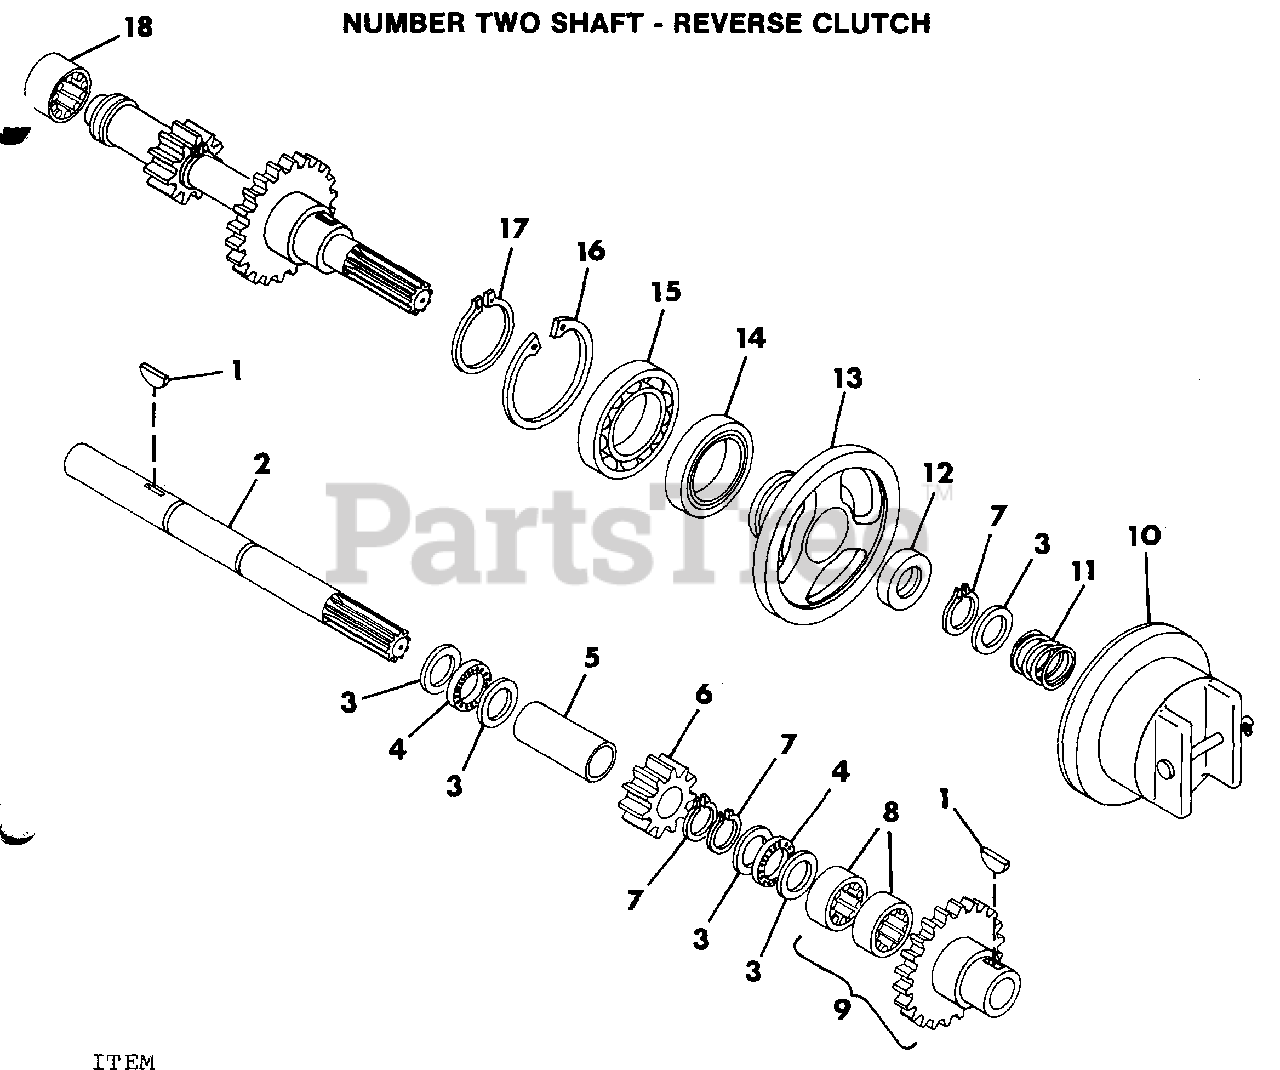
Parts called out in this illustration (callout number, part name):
1	KEY, WOODRUFF .187X.625 HARD #61
2	SHAFT, SPLINED REVERSE CLUTCH
3	RACE, BEARING THRUST
4	BEARING, NEEDLE THRUST
5	SPACER, #2 SHAFT
6	GEAR, 10 DP 16 TEETH X.750
7	RING, RETAINING .750 SHAFT
8	BEARING, NEEDLE .750X1.000X.500
9	ASM, REVERSE GEAR AND BEARING
10	NUMBER 11 - FWD-REV CLUTCH ASM.
11	SPRING, COMP. TYPE 1.0X.80X36 16/IN.
12	SEAL, OIL .750X1.625X.250
13	HUB, CLUTCH
14	SEAL, OIL 2.250X3.005X.375
15	BEARING, BALL 1.968X3.149X.629
16	RING, RETAINING 3.156 BORE
17	RING, RETAINING 1.969 SHAFT
18	BEARING, NEEDLE .75X1.00X.75
